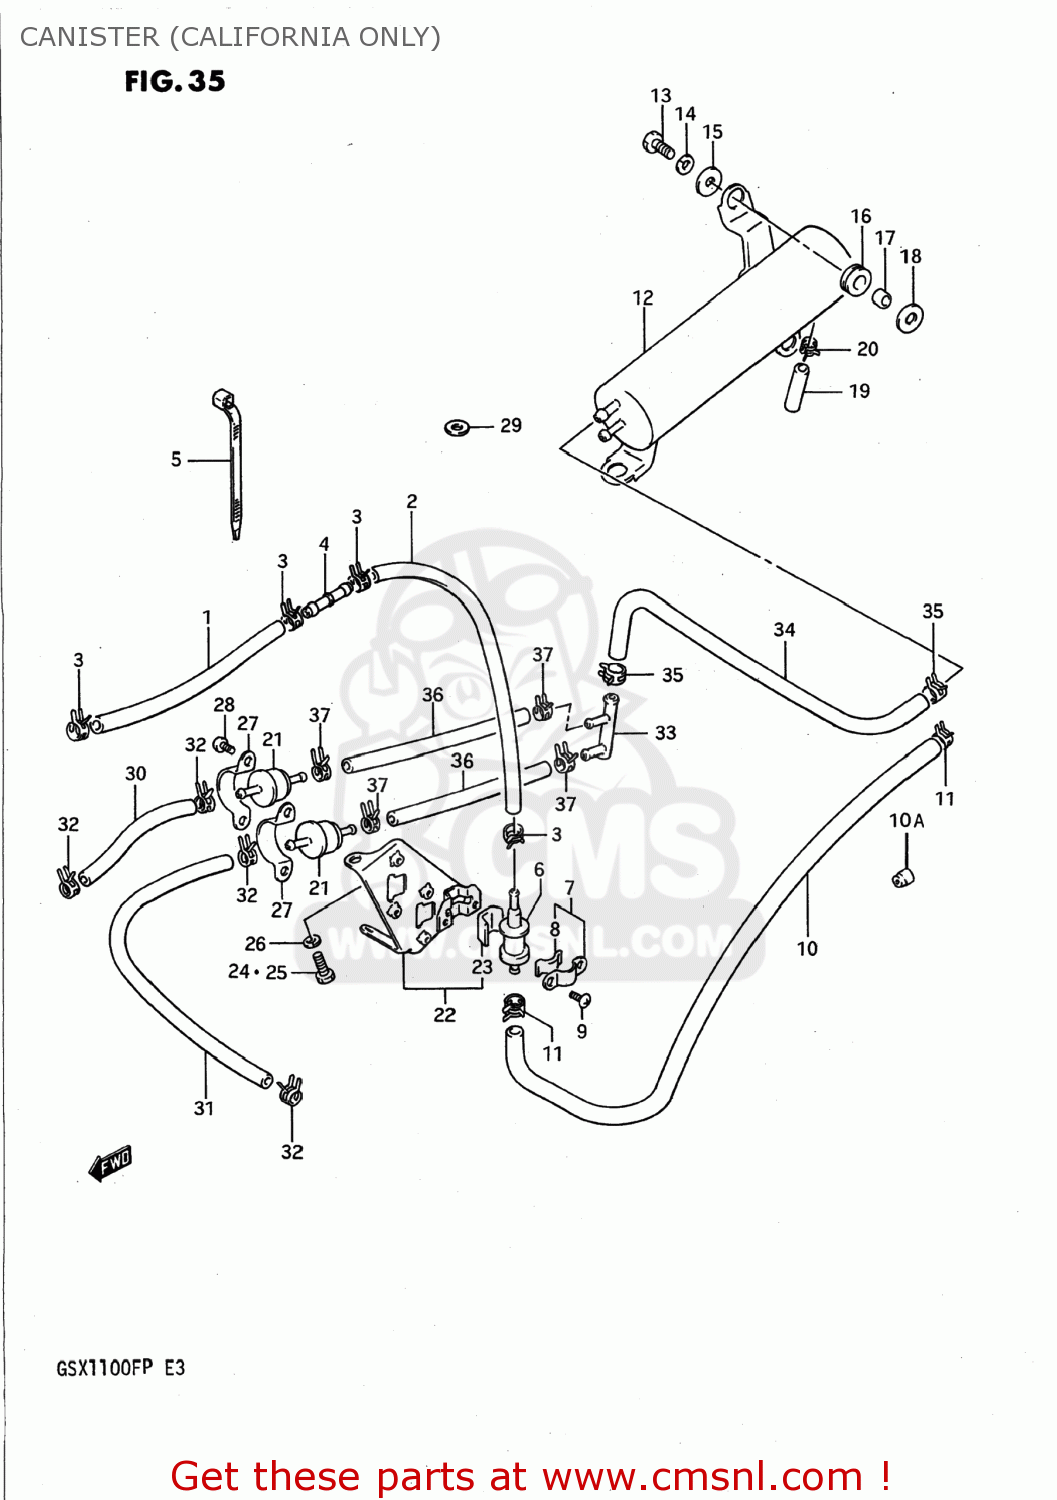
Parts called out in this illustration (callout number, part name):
1	HOSE
2	HOSE
3	(CA) CLIP
4	UNION
5	CLAMP(L:125)
6	VALVE,FUEL TANK BREATHER
7	PLATE,FUEL TANK BREATHER NO.2
8	CUSHION
9	SCREW
10	HOSE (L:330)
10A	NOZZLE
11	(CA) CLIP
12	CANISTER COMP,CHARCOAL
13	BOLT
14	WASHER,LOCK
15	WASHER (6.5X20X1.2)
16	CUSHION
17	SPACER(6.1X9X7.5)
18	WASHER
19	HOSE (7X12X300)
20	(CA) CLIP
21	VALVE,CANISTER PURGE
22	BRACKET,CANISTER
23	CUSHION
24	BOLT
25	BOLT
26	WASHER,LOCK
28	SCREW
29	WASHER (12.5X24X1.6)
30	HOSE
31	HOSE (5.4X11.4X600)
32	(CA) CLIP
33	SEPARATOR
34	HOSE(L:350)
35	CLAMP
36	HOSE
37	(CA) CLIP
